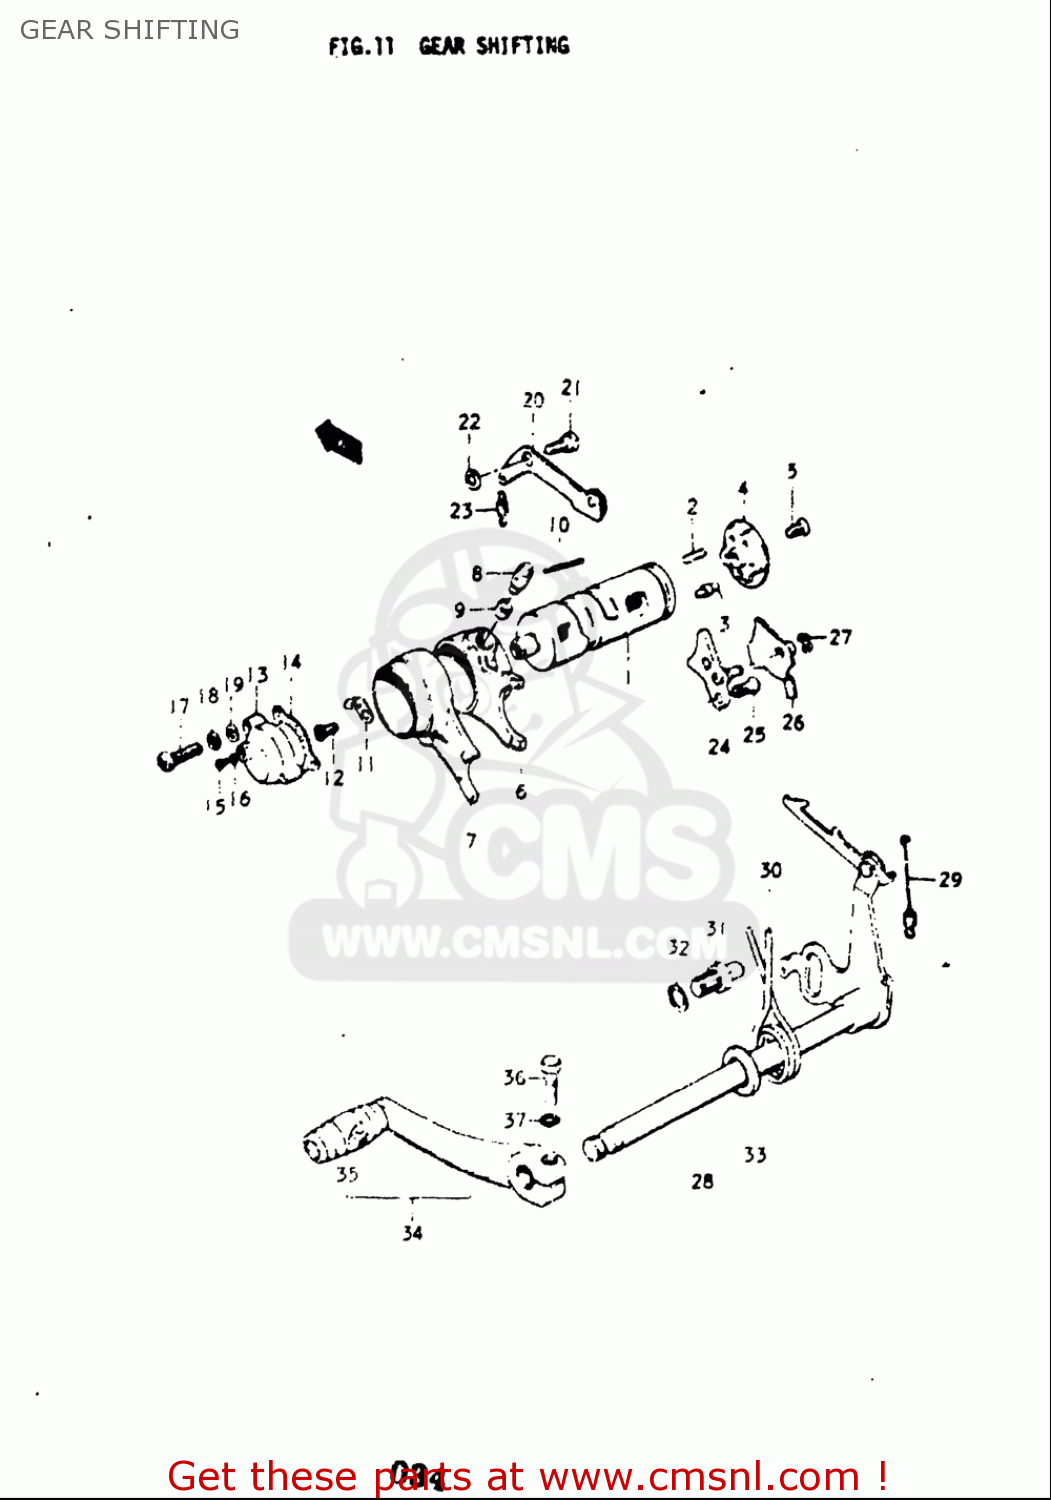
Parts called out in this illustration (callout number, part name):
2	PIN(4X20)
3	PIN
5	SCREW
6	FORK,GEAR SHIFT NO.1
7	FORK,GEAR SHIFT NO.2
8	PIN
9	SPACER(6X9.8X6)
10	PIN
11	CONTACT,GEAR SHIFT SWITCH
12	SCREW
13	BODY,CHANGE SWITCH
14	GASKET,GEAR SHIFT SWITCH (NAS)
15	SCREW
16	WASHER
17	SCREW
18	WASHER,LOCK
19	WASHER
21	BOLT(6X16.1)
22	WASHER(6.5X16X2.3)
24	GUIDE,GEAR SHIFT CAM
25	SCREW
26	PAWL,GEAR SHIFT CAM STOPPER
27	E RING
28	SHAFT,GEAR SHIFT
29	SPRING
30	SPRING
32	WASHER,LOCK
33	SEAL,OIL (12X22X9)
34	LEVER ASSY,GEAR SHIFT
35	RUBBER,GEAR SHIFT PEDAL
36	BOLT
37	WASHER,LOCK
